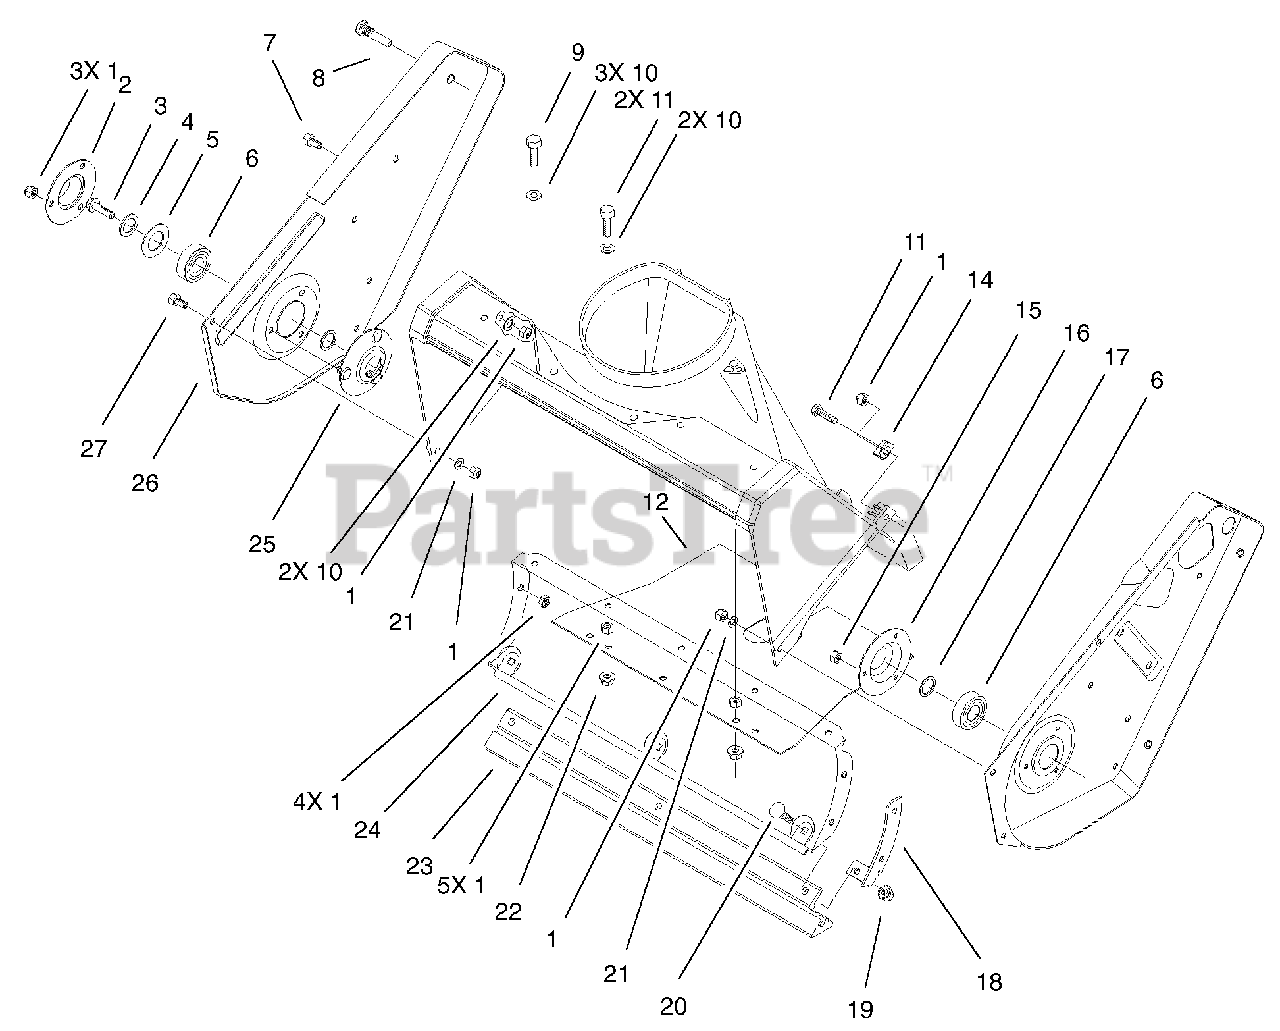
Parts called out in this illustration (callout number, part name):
1	NUT-LOCK, NI
2	RETAINER-BEARING
3	SCREW-HHF
4	WASHER-FLAT
5	WASHER-RUBBER
6	BEARING-BALL
7	SCREW-HH
8	PIN-ROTOR
9	SCREW-HH
10	WASHER-FLAT
11	SCREW-HH
12	COVER-BOTTOM
14	BRACKET-HOUSING
15	NUT-LOCK
16	FLANGE-BEARING
17	WASHER-THRUST
18	BRACKET-HOUSING, LOWER
19	NUT-KEPS
20	SCREW-CARR
21	WASHER-FLAT
22	NUT-LOCK, HHF
24	HOUSING-LOWER
25	FLANGE-BEARING
26	PLATE-SIDE, RH
